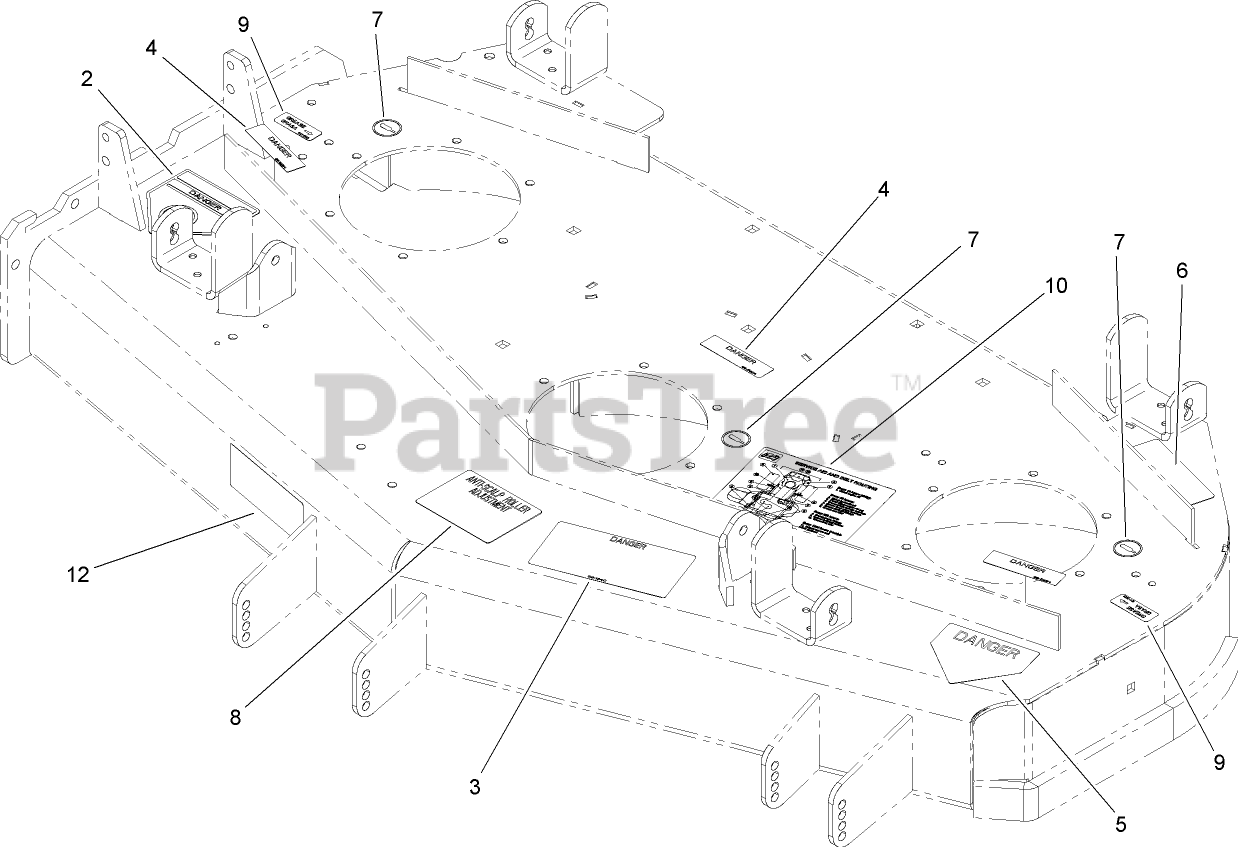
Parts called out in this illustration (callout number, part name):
2	DECAL-DANGER
3	DECAL-DANGER, THROWN OBJECT
4	DECAL-COVER, MISSING
5	DECAL-DANGER
6	DECAL-TORQUE
7	DECAL-GREASE
8	DECAL-SCALP, ANTI
9	Decal-Grease
10	DECAL-AID, SERVICE
